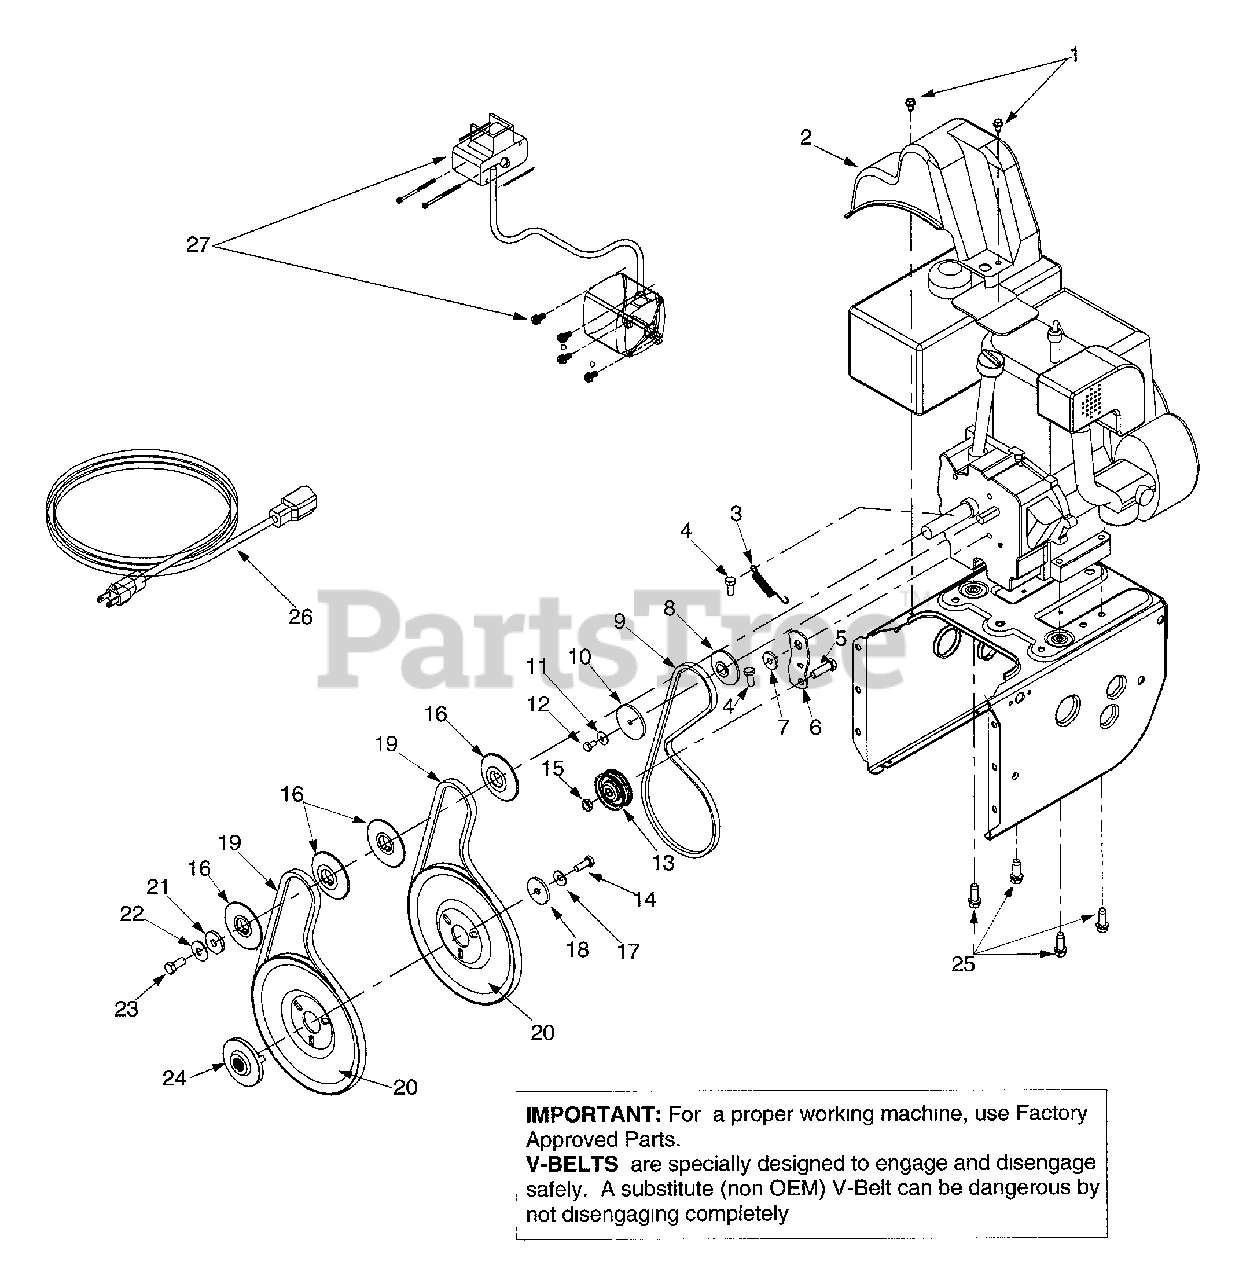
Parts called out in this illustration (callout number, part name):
1	Hex Washer Screw 1/4-20 x .625
2	Belt Cover
3	Extension Spring
4	Hex Screw 5/16-24 x .75
5	Hex Cap Screw 3/8-16 x 1.25
8	Pulley Half
9	V-Belt
10	Pulley Half
11	Bell Washer
12	Hex Cap Screw 1/4-28 x .50
13	Flat Idler
14	Lock Hex Cap Screw 5/16-24
15	Lock Jam Nut 3/8-16
16	Pulley Half
17	Bell Washer
18	Flat Washer
19	Belt
20	Auger Pulley
21	Flat Washer 3/8 x 1.25 OD
22	Bell Washer
23	Hex Cap Screw 3/8-24
24	Adapter Pulley
25	Hex Screw 3/8-16 x 1.0
26	Extension Cord
27	Electric Start
